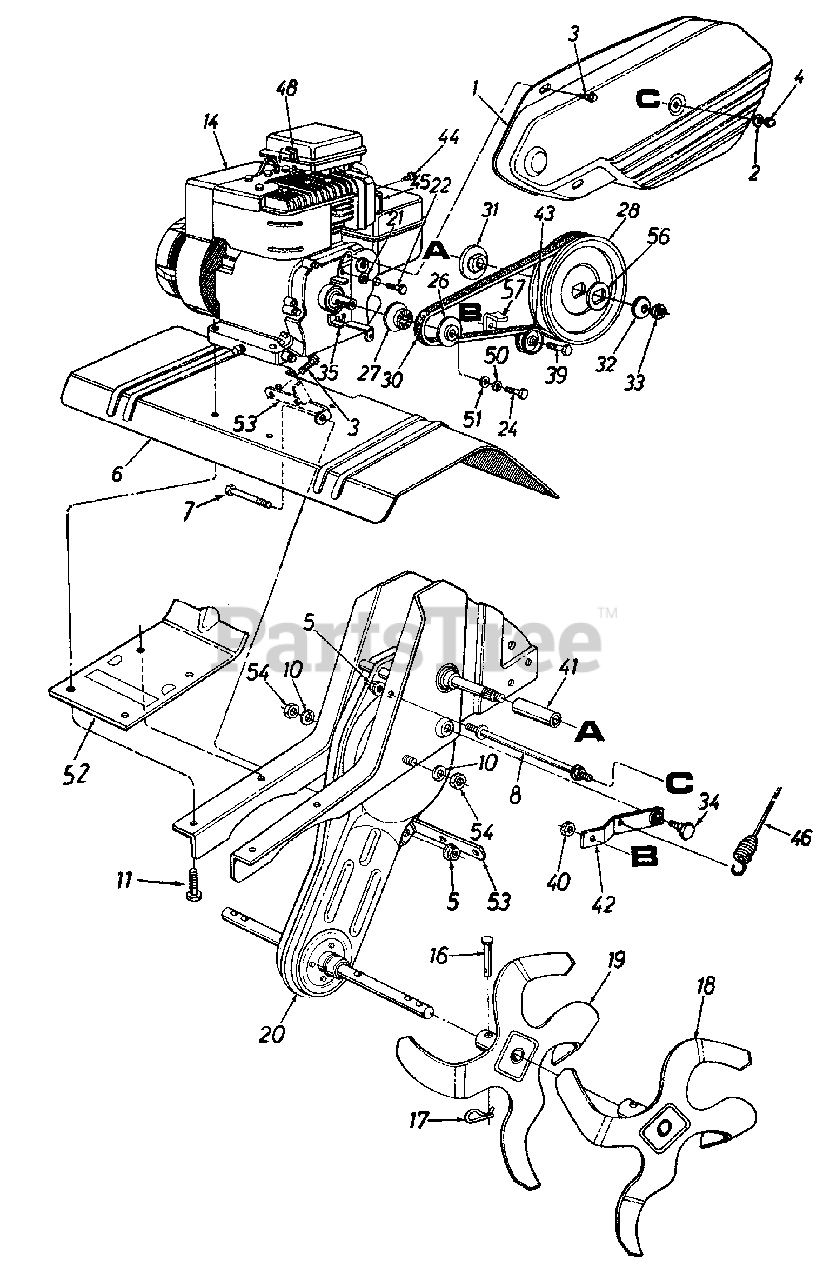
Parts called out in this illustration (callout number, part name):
1	Belt Cover
2	Fl-Wash. .266" I.D. x .625" O.D.
3	Hex Wash. Hd. TT-Tap Scr. 1/4-20 x .5" Lg.
4	Hex L-Stop Nut 1/4-28 Thd.
5	Hex Flange Top L-Nut 5/16-18 Thd. (Gr. 5)
7	Hex Bolt 5/16-18 x .75" Lg.*
8	Belt Cover Bolt
10	L-Wash. 7/16" I.D.
11	Hex Wash. Hd. TT-Tap Scr. 3/8-16 x 1.25" Lg.
14	Engine
16	Clevis Pin .375" Dia. x 1.62" Lg.
17	Internal Cotter Pin
20	Chain Case Ass'y. Comp.
21	L-Wash. 5/16" I.D.
22	Hex Bolt 5/16-24 x .5" Lg.
24	Hex Bolt 3/8-24 x 1.25" Lg.
26	Outer Engine Pulley Half
27	Inner Engine Pulley Half
28	Fl-Pulley 6" Dia.
30	"V"-Belt
31	Pulley Mounting Adapter
32	Bell-Wash. .535" I.D. x 1.5" O.D.
33	Hex Jam Nut 1/2-20 Thd. (Gr. 5)
34	Shld. Bolt 5/16-18 Thd.
39	Hex Cap Bolt 3/8-16 x 1.25" Lg.
40	Hex Cent. Jam Nut 3/8-16 Thd.
41	Spacer .64" I.D. x 2.4" Lg.
44	Hx Self-Tap Scr. #8-32 x .38" Lg.
45	Muffler Deflector
46	Clutch Control Cable
48	Spark Plug Boot
50	L-Wash. 3/8" I.D.
51	Fl-Wash. 3/8" I.D. x 1" O.D.
52	N Engine Plate
54	Hex Nut 7/16-20 Thd.
56	Bearing Retainer Washer
57	Belt Keeper
